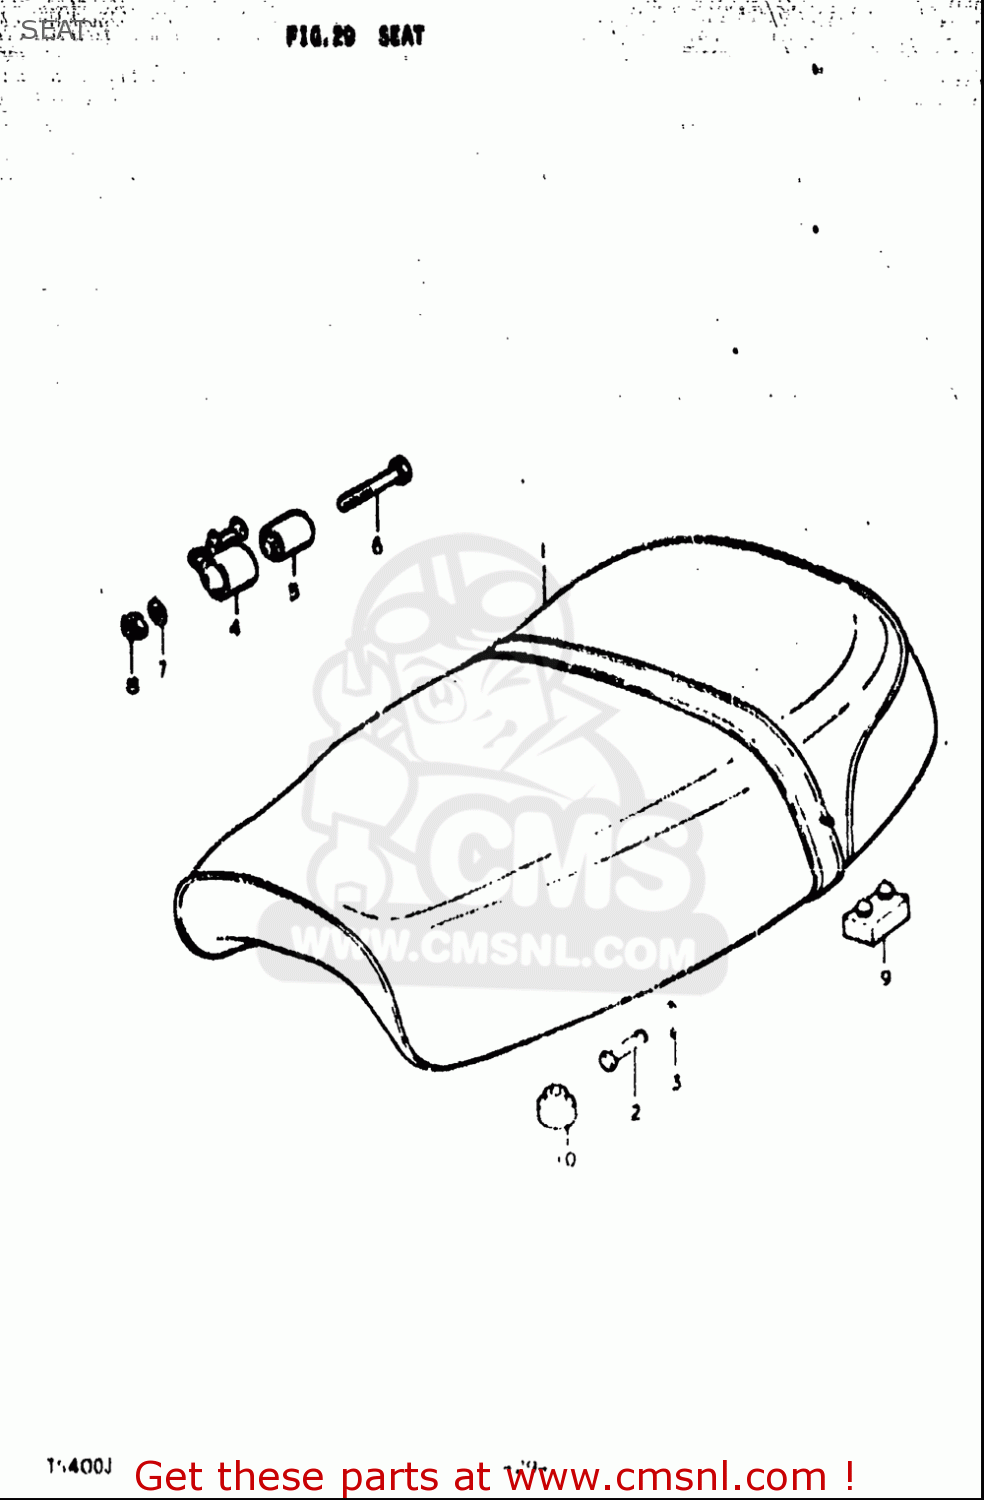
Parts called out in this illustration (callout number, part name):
2	PIN
3	PIN
4	STRIKER,SEAT LOCK
5	BUSHING
6	BOLT
7	WASHER,LOCK
8	NUT
9	CUSHION
10	CUSHION(11.5X22X20)
